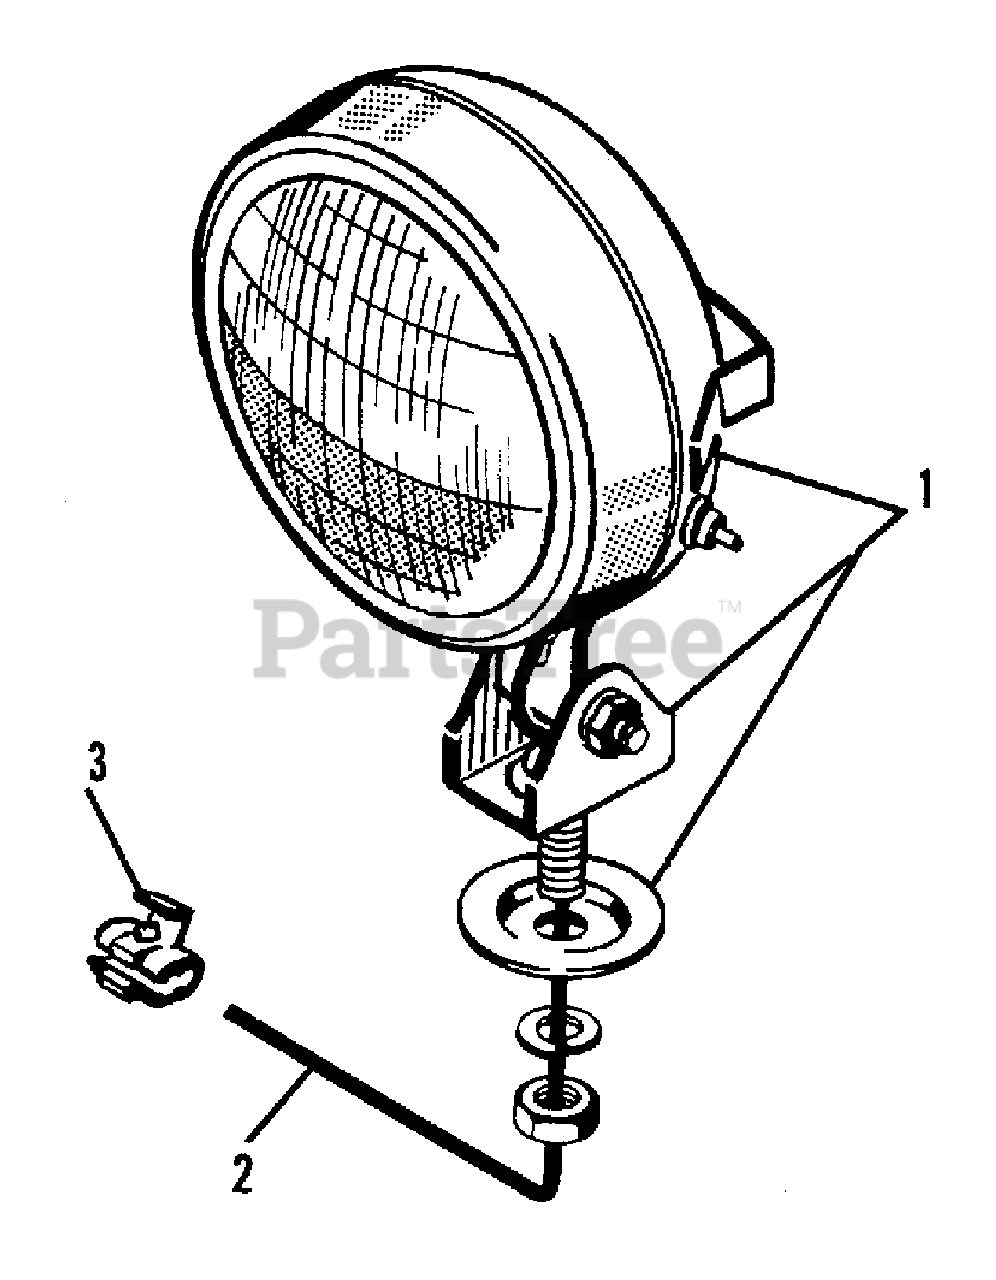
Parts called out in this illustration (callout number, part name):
1	LIGHT ASSEMBLY, Rear Work
1	LIGHT ASSEMBLY, Seal Beam
2	LEAD, Rear, Work Light
3	CONNECTOR, Self-Stripping
